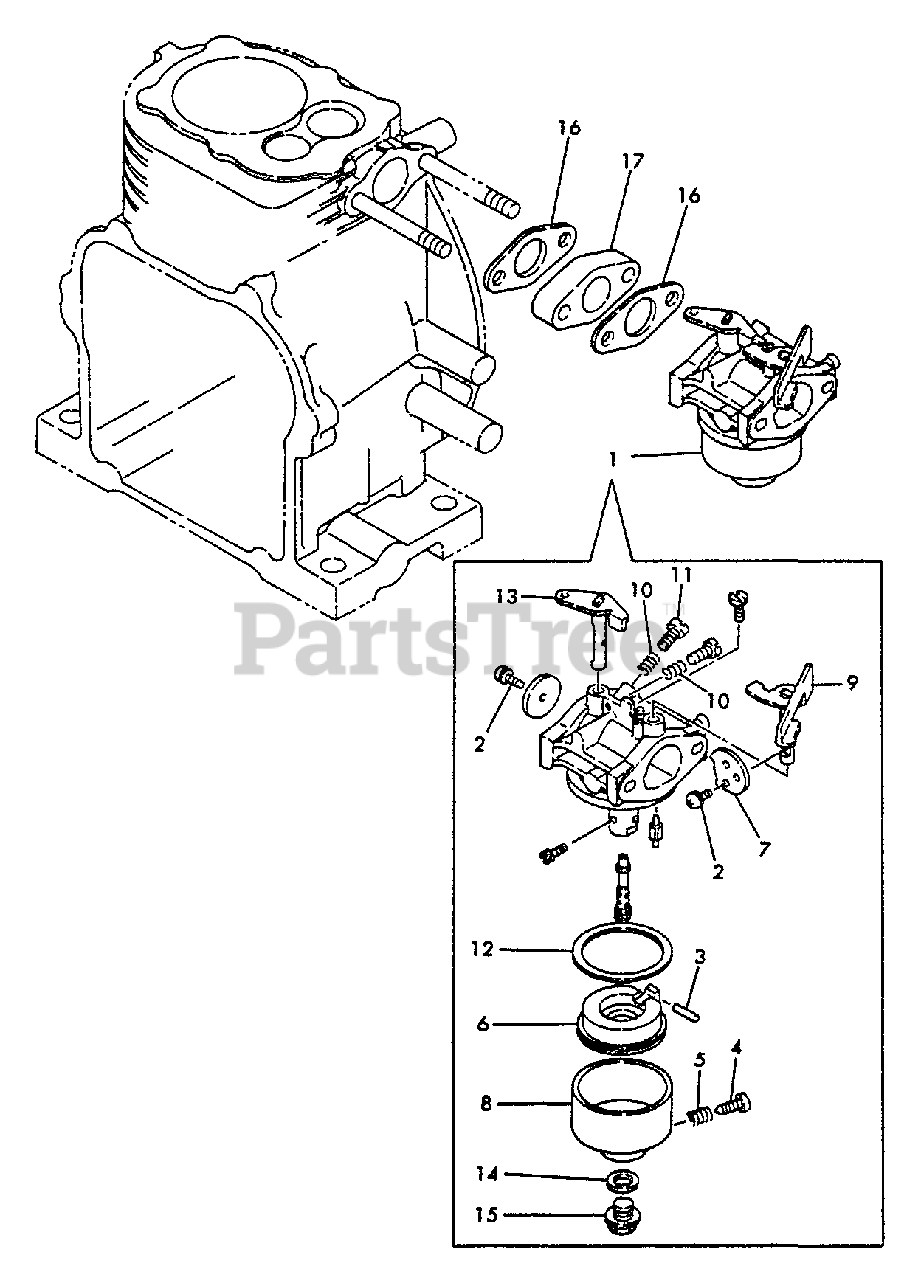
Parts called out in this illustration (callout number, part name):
1	CARBURETOR
3	PIN
4	SCREW
6	FLOAT ASSY
7	VALVE, CHOKE
8	BODY, CHAMBER
9	SHAFT, CHOKE
11	SCREW, PILOT
12	GASKET
13	SHAFT, THROTTLE
14	WASHER
15	BOLT
16	GASKET, INTAKE
17	SPACER, CARBURETOR
